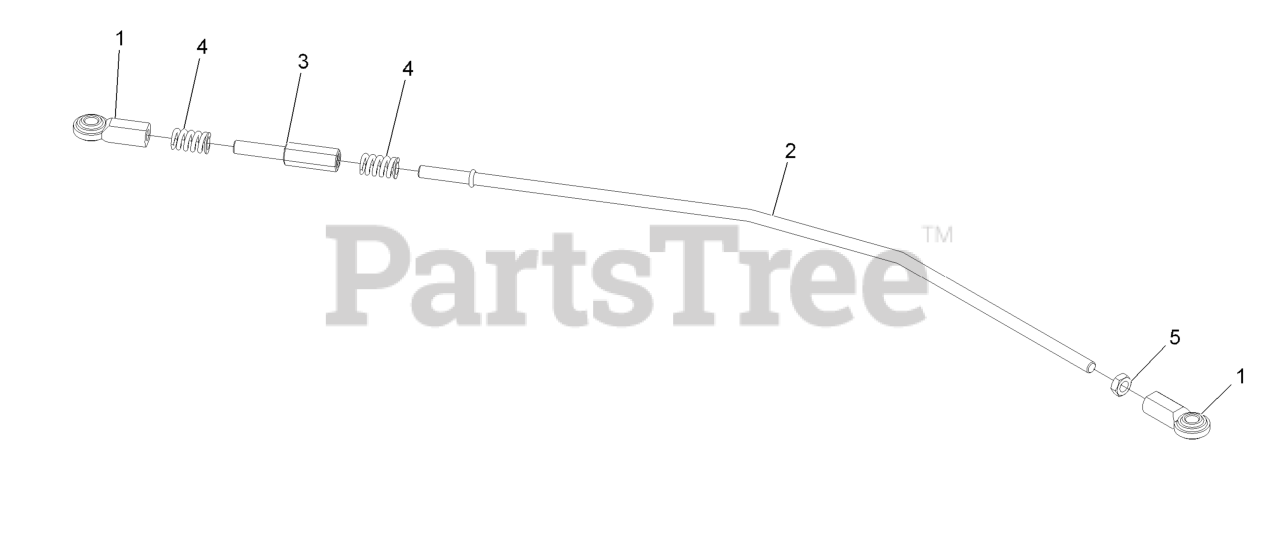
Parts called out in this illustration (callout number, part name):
1	JOINT-BALL, END
2	LINK-LOWER,MOTION CONTROL
3	ROD-ADJUSTMENT
4	SPRING-COMPRESSION
5	NUT-HJ
